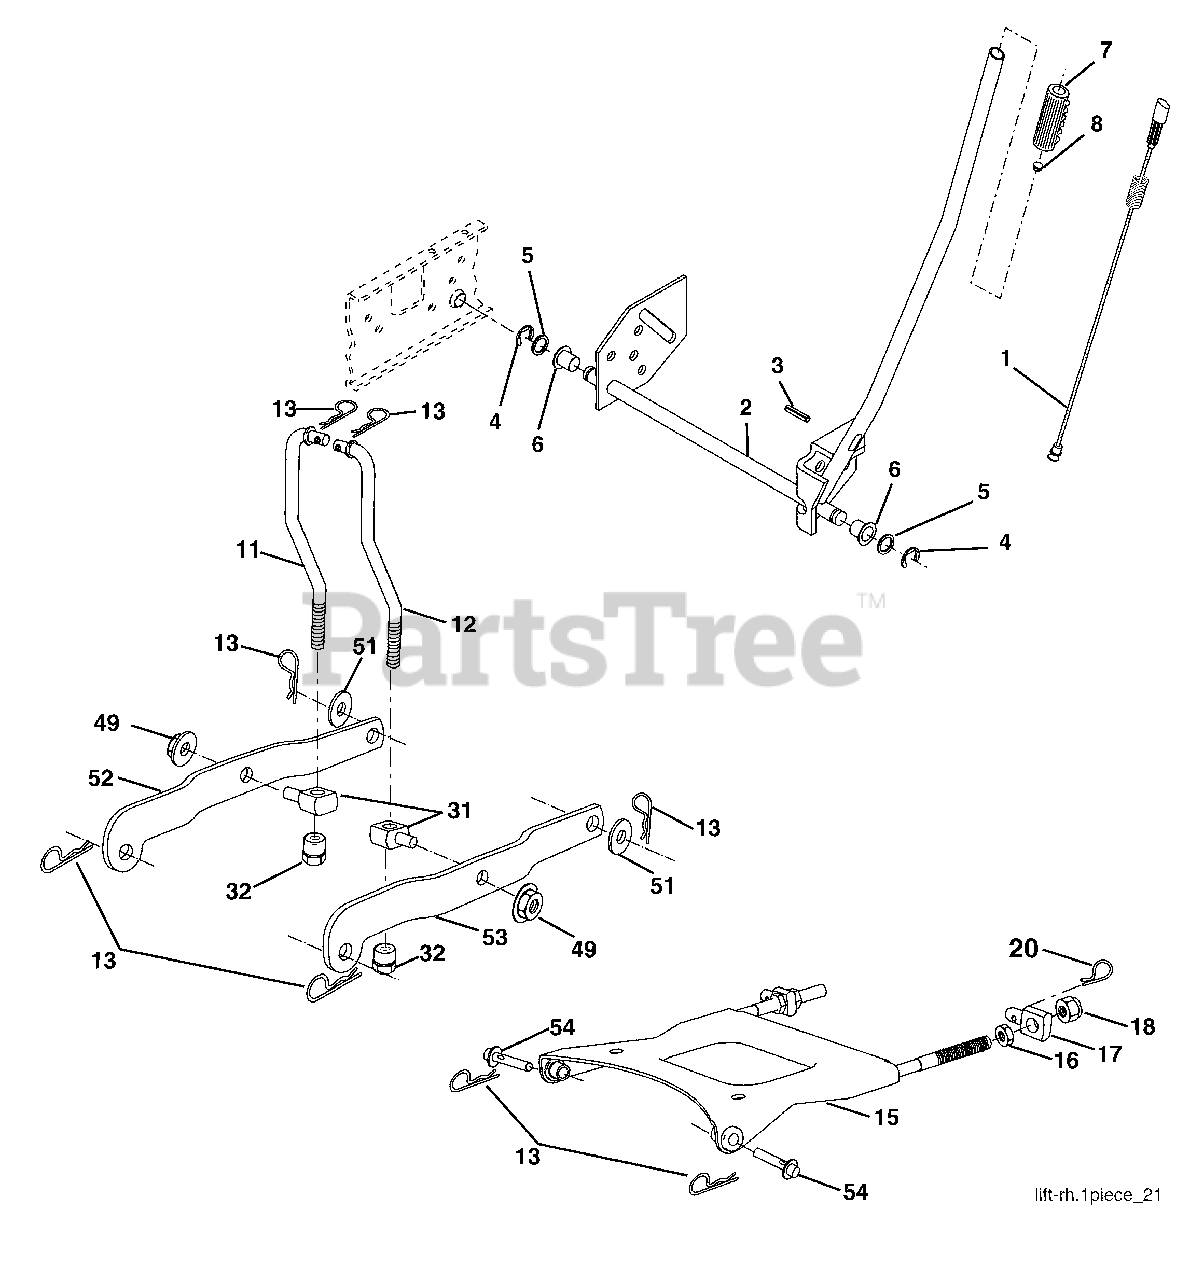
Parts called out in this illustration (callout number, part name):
1	Wire Asm Inner W/plunger 17 32
2	Shaft Asm Lift LH Inf Hgt P/L
3	Pin Groove 1 500 Zinc
4	E Ring #5133-62
5	Washer 21/32 x 1 x 21 Ga.
6	Bearing Nylon Blk 629 Id
7	Grip Handle
8	Button Plunger
11	Link Lift LH
12	Link Lift RH
13	Retainer Spring
15	Plate Asm Suspension Front
16	Nut Jam Hex 1/2-13 unc
17	Trunnion Blk Zinc
18	Nut Lock W/wsh 1/2-13 unc
20	Retainer Spring
31	Trunnion Suspension Arm
32	Nut Lift Link 7/16-20
49	Nut Hex Flange Lock
51	Washer 17/32 x 7/8 x 16 Ga.
52	Arm Suspension Rear LH
53	Arm Suspension Rear RH
54	Pin Flange
